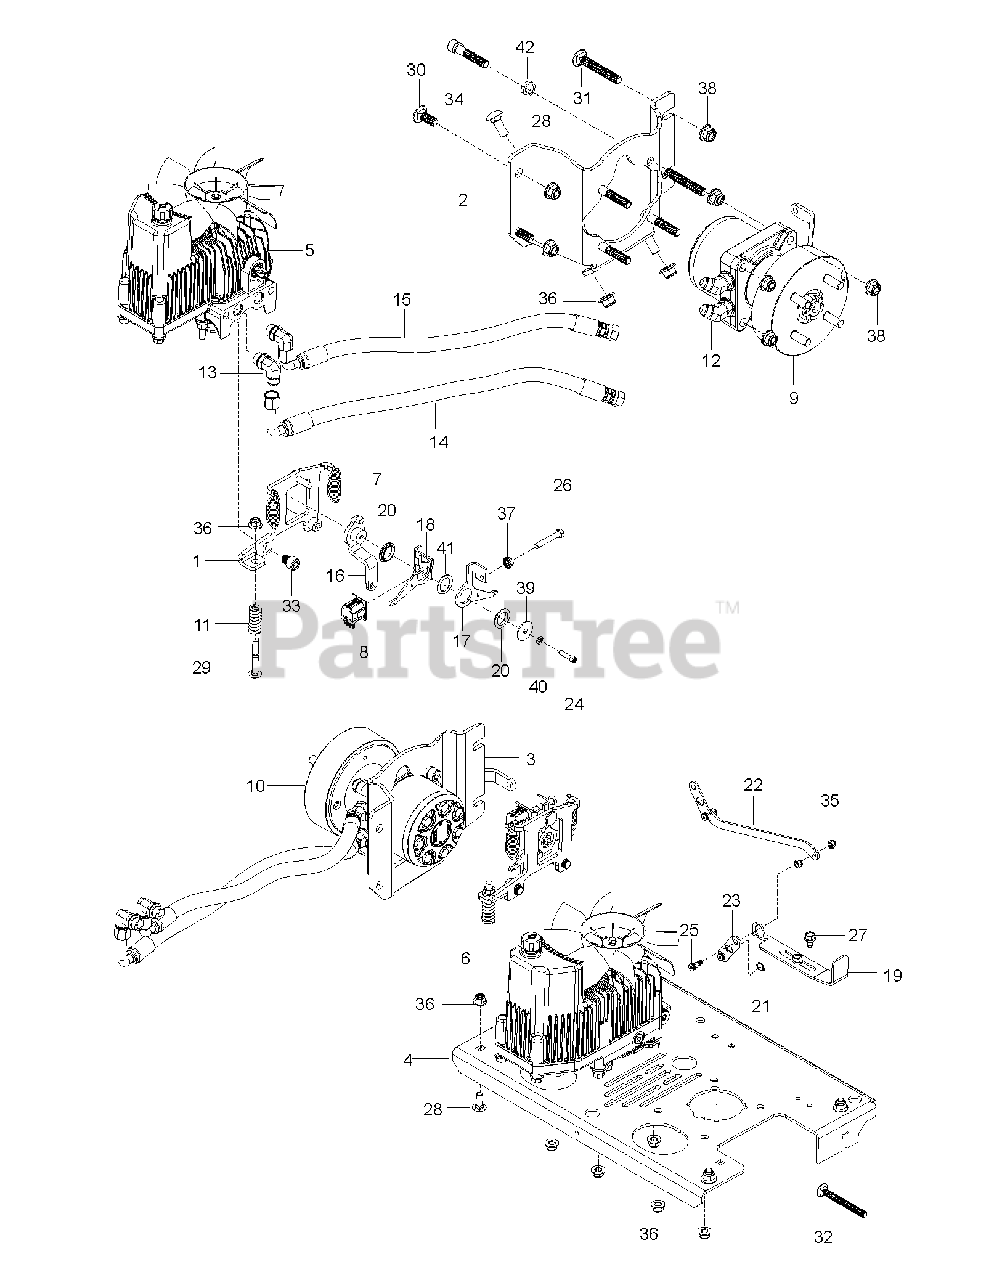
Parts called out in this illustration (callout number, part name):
1	BRACKET STATIONARY; RTN; WELDM
2	BRACKET MTG, MOTOR LH, BLACK,
3	BRACKET MTG, MOTOR RH, BLACK,
4	PLATE MTG, PUMP BLACK, X431
5	PUMP 12CC LH
6	PUMP 12CC RH
7	SPRING RTN; STAND ON
8	SWITCH SEAT, 4 PIN NC/NO
9	HYDRAULIC MOTOR 195CC, LH
10	HYDRAULIC MOTOR 195CC, RH
12	FITTING.45.ELB.7/8-14.SAE.ORB
13	FITTING.90ELB.3/4-16.SAE.ORB
14	HYDRAULIC.HOSE.LOWER
15	HYDRAULIC.HOSE.LOWER
16	ARM CONTROL; STAND ON; RTN
17	ARM.RTN.BRACKET.L.SCREW.LH
18	ARM.RTN.BRACKET.L.SWITCH.LH
19	PULL.ROD.BYPASS.MS.X431
20	BUSHING FLANGE; PLASTIC; IGUS
21	CLIP C; EXTERNAL .461 ID X .03
22	LINK.PNT.CROSS.PUMP.BYPAS.EDIP
23	PIVOTING.PNT.ARM.PMP.BYPS.EDIP
24	SCREW HEXALOBULAR SOCKET HEAD
25	Bolt, 5/16 X .25 Shoulder
26	HCS 5/16-18 X 2 TPBLT GR 5 ZD
27	BOLT.SHOULDER.5/16-18X
28	RHSNB 3/8C X 1
29	Roundhead Squareneck Bolt, 3/8-16 X 2-1/2
30	SCREW RHSNB, 1/2-13, GR5 ZY 1-
31	SCREW RHSNB, 1/2-13, GR5 ZY 3-
32	SCREW RHSNB 3/8-16 GR5 ZY 3.5"
33	Socket Head Capscrew
34	SCREW SHCS, 1/2-13 X 2-1/2"L
35	RP_NUT 1/4-20 NYLOC
36	NUT 3/8-16 HEX FLG NYLOC ZD
37	NUT 5/16C WHIZ
38	NUT, 1/2-13 HEX FLG NYLOC ZD
39	WASHER FENDER 1/4"X1.25"X0.08"
40	LOCKWASHER
41	WASHER PLAIN 0.88"X1.28"X0.062
42	LOCKWASHER .512 ID, .733 OD, .
